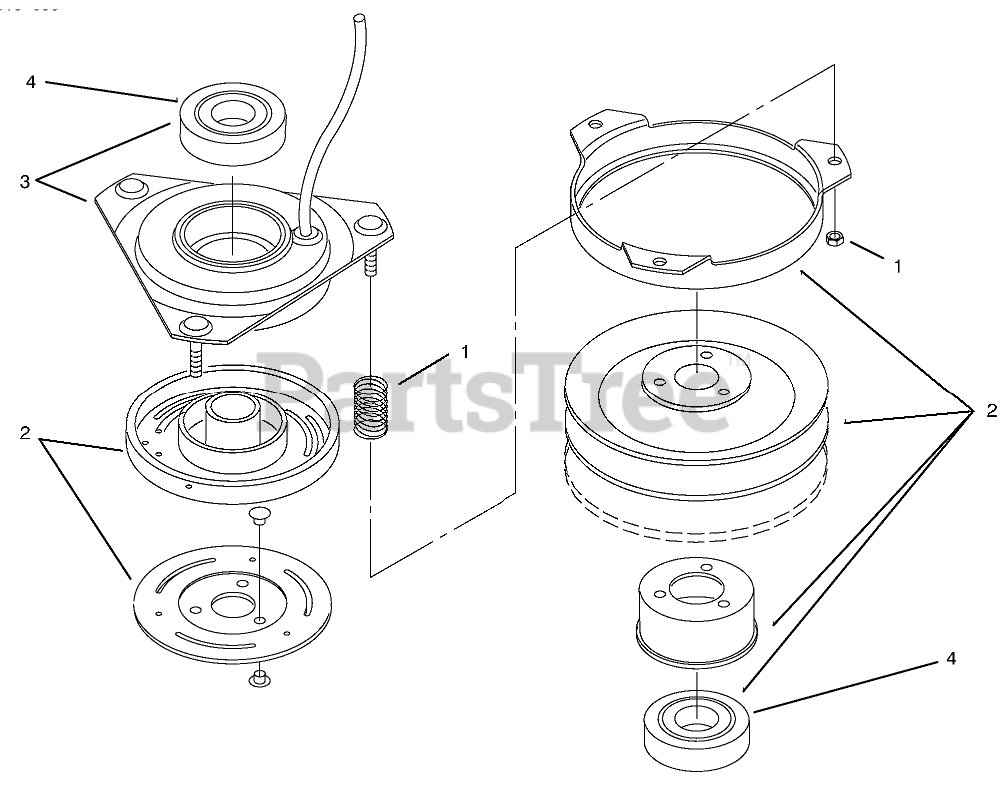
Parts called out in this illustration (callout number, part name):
1	ACCESSORY PKG SRVC PART
2	Rotor ASM w/Bearing (Only On: 72064)
2	Rotor & Armature ASM (Only On: 72046)
3	FIELD ASSY (SRVC PART)
4	BEARING-ELEC CLUTCH
